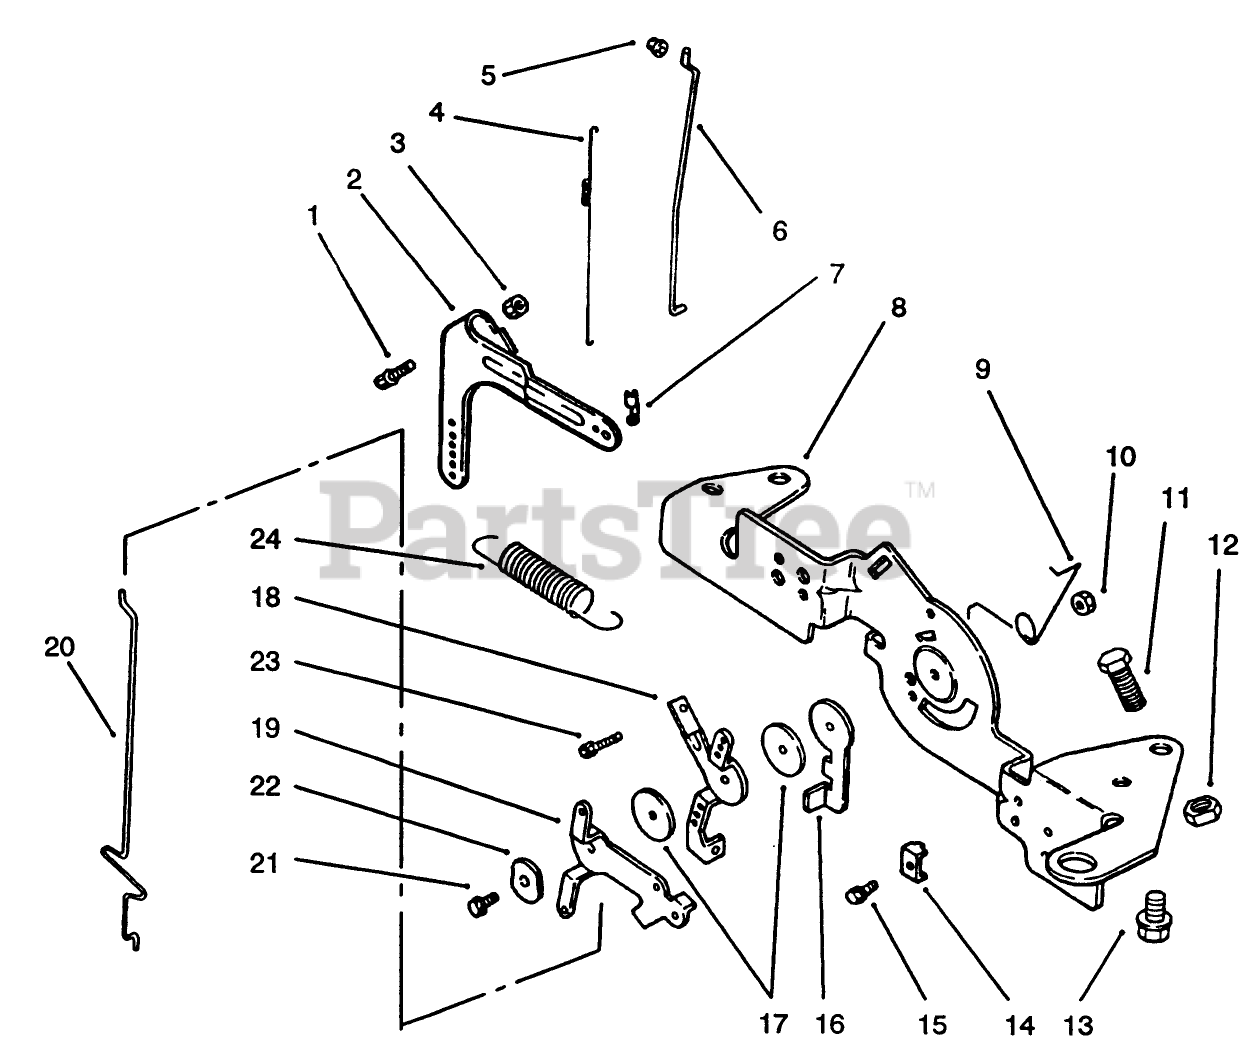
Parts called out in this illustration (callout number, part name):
2	Lever-Governor (Only On: 72103)
4	Spring-Linkage
5	Bushing
6	Linkage-Throttle (Only On: 72103)
7	Bushing-Linkage
8	Bracket-Control
9	Spring-Choke Return
16	Lever-Throttle Actuator
18	Lever-Throttle Control
19	Lever-Choke
20	Linkage-Choke (Only On: 72103, 72083)
22	Washer-Wave
24	Spring-Governor
